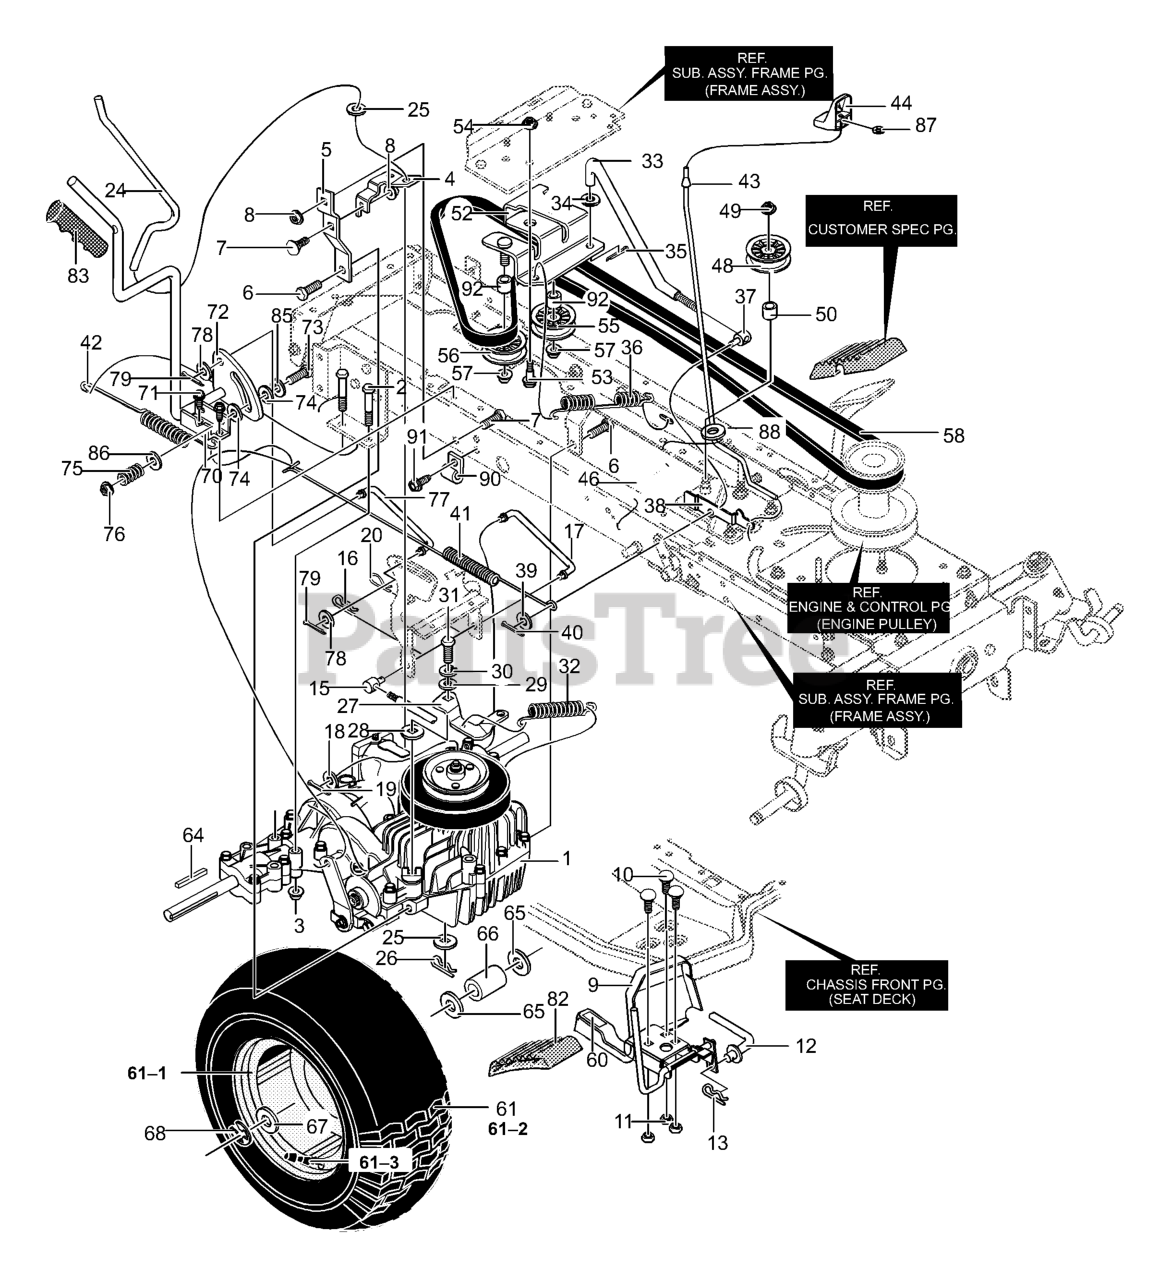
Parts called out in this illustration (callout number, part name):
1	Transaxle, Peerless **
2	SCREW, 5/16-18 x 2.50
3	NUT, 5/16-18
4	BRACKET, DISCONNECT
5	TORQUE STRAP -RIGHT
6	SCREW, 5/16-18 x 0.75
7	BOLT, CARRIAGE 5/16-18X .63
8	NUT, 5/16-18
9	WP, PEDAL ASSY HYDRO
10	BOLT, 5/16-18X .75
11	NUT, HEX 5/16-18
12	ROD, PEDAL LINK
13	PIN, HAIR
15	ADJUST NUT 1/2-13
16	PIN, HAIR
17	ROD HYDRO LINK
18	WASHER, FLAT
19	PIN, COTTER
20	PIN, HAIR
24	ROD, DISCONNECT
25	WASHER, FLAT
26	PIN, COTTER
27	ARM, DISCONNECT
29	WASHER, FLAT
30	WASHER
31	SCREW, 1/4-28 X.75
32	SPRING, EXTENSION
33	ROD, CLUTCH
34	WASHER, FLAT
35	PIN, COTTER
36	SPRING, CLUTCH
37	NUT, ADJUSTING
38	LATCH, PARKING BRAKE
39	WASHER, FLAT
40	PIN, COTTER
41	SPRING, EXTENSION
42	SPRING, EXTENSION
43	ROD- PARKING BRAKE
44	PARKING BRAKE KNOB
46	SPRING - EXTENSION
48	PULLEY, IDLER
50	SPACER 1/2 TO 17MM
52	ASSEMBLY, BRACKET IDLER
54	NUT, 3/8-16
55	PULLEY, IDLER
56	PULLEY, IDLER
57	NUT, 3/8-16
58	BELT, MOTION DRIVE HYDRO
60	PAD, TOE SANDPAPER
61	TIRE & RIM 20X10.-8
61-1	VALVE STEM
64	KEY, SQUARE
65	WASHER, FLAT
67	WASHER, FLAT
70	BRACKET, HAND CONTROL
72	LEVER, HAND CONTROL
74	WASHER, FRICTION
75	SPRING - COMPRESSION
76	NUT, 5/16-18
77	LINK, CRUISE CONTROL
78	WASHER, FLAT
79	PIN, COTTER
82	PAD, SPEED CONTROL
85	WASHER, FLAT
86	WASHER, FLAT
87	PUSHNUT
88	WASHER, FLAT
90	RETAINER WIRE
92	SPACER 1/2 TO 17MM
